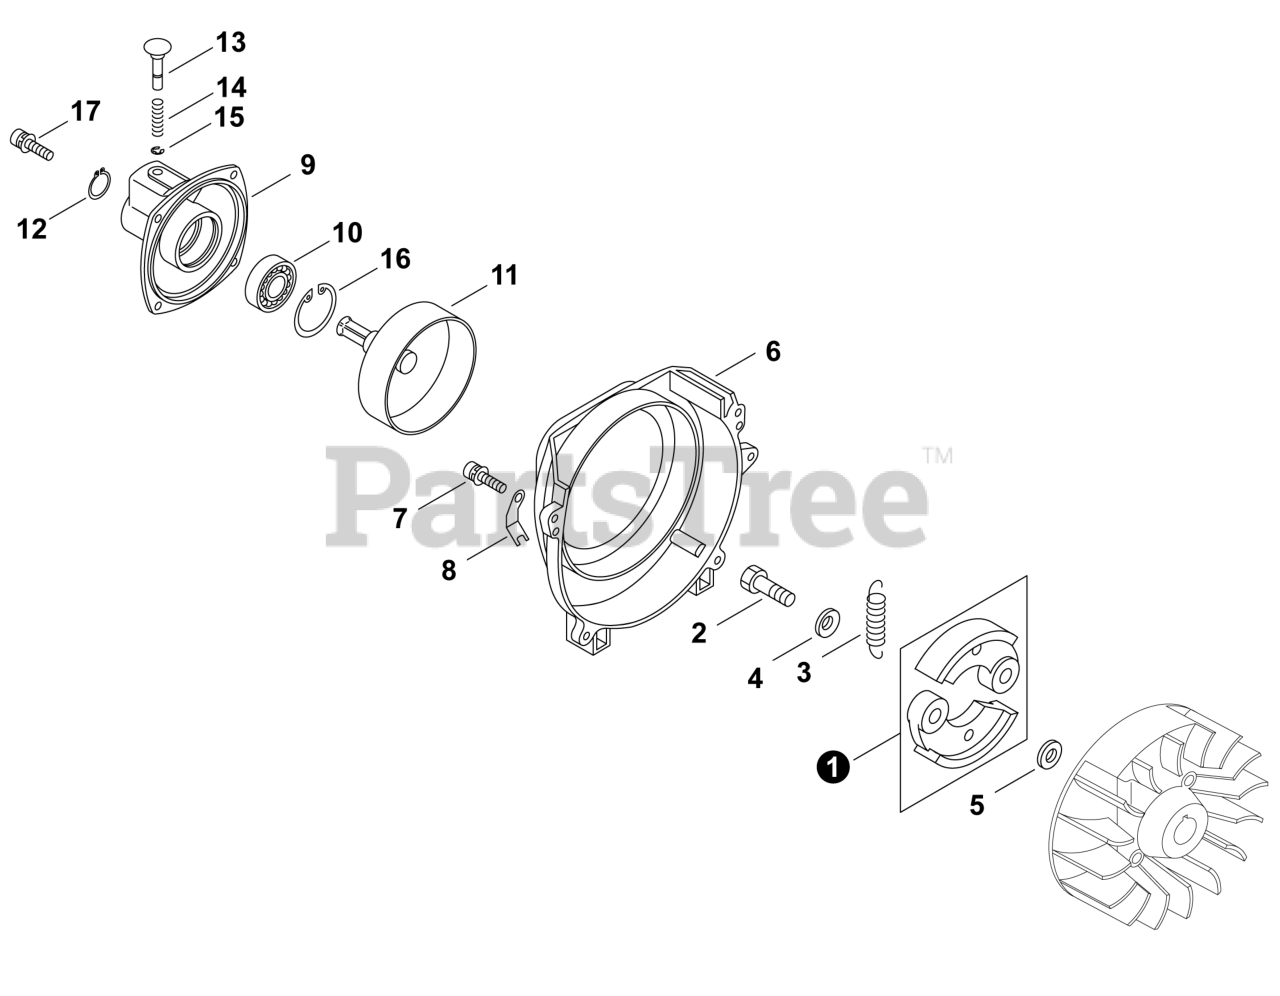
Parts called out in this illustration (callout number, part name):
1	SHOE SET, CLUTCH
2	BOLT, CLUTCH
3	SPRING, TENSION
4	WASHER, WAVE
5	WASHER 8.2×17×1.6
6	COVER, FAN
7	BOLT 5×20
8	HOLDER, CABLE
9	CASE, CLUTCH
10	BEARING, BALL
11	DRUM, CLUTCH
12	RING, SNAP
13	PIN, LOCK
17	BOLT 5×20
